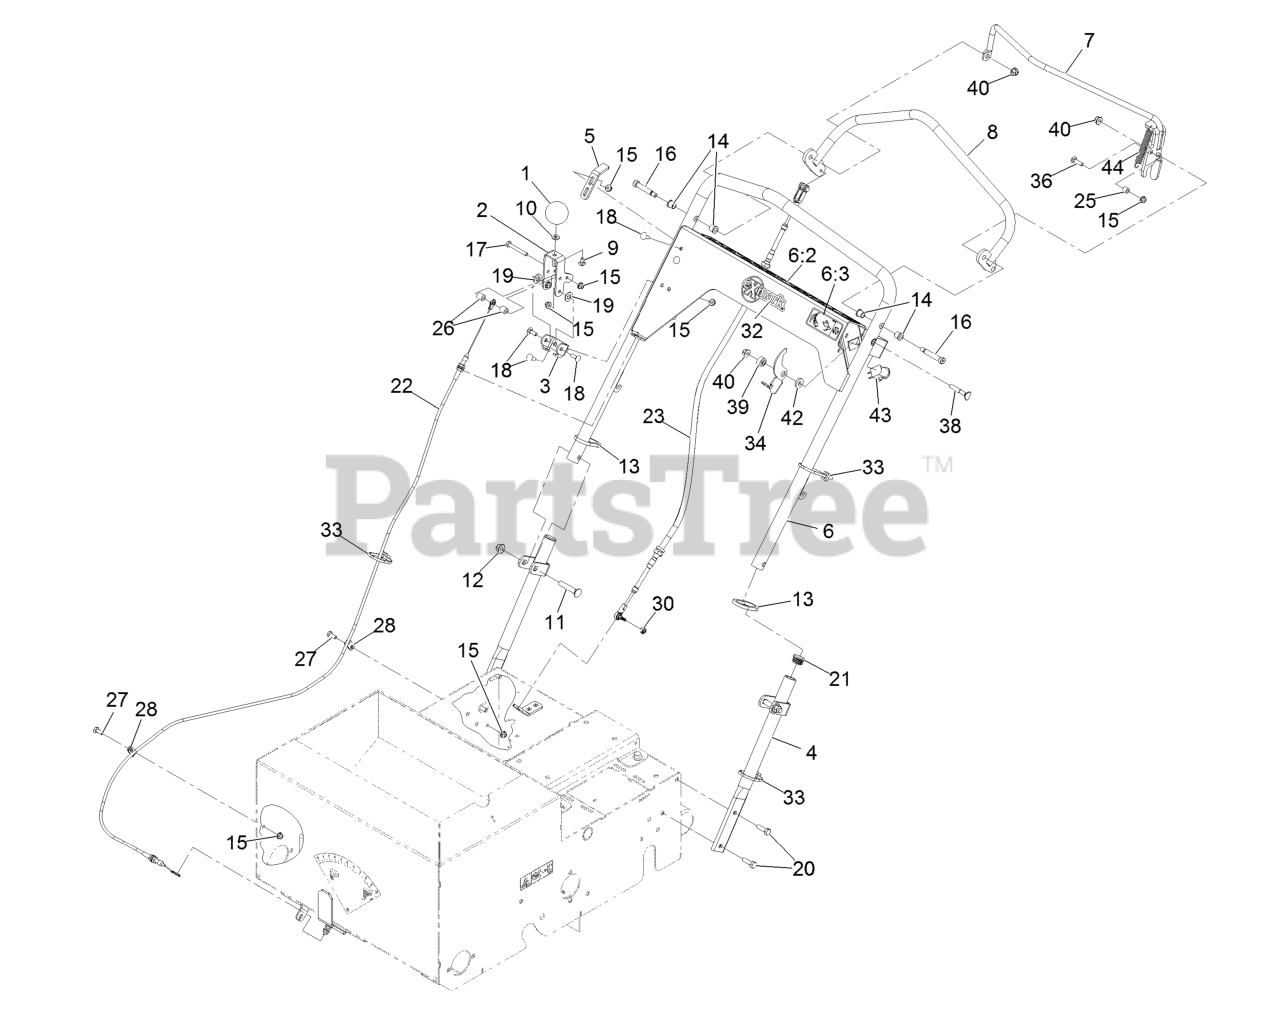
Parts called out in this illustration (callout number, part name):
1	KNOB-RATE, FLOW
2	LEVER-ADJUST, FLOW
3	BRACKET-ADJUST, FLOW
4	HANDLE-LOWER
5	BRACKET-ADJUST, DRIVE
6:2	DECAL-CONTROL PANEL, SEED
6:3	DECAL-SAFETY LATCH
8	HANDLE-DRIVE
9	SCREW-CARR
10	WASHER-FLAT
11	SCREW-HH
12	NUT-HF, NI
13	RING-HANDLE LOCK
14	BEARING
16	SCREW-SHOULDER
17	SCREW-HH
18	BOLT-CARR
19	WASHER-PLAIN
20	SCREW-HH
22	CABLE-FLOW, SEED
23	CABLE-PUSH PULL
27	SCREW-HH
28	CLAMP-R
30	NUT-LOCK
33	TIE-CABLE
34	LATCH-BAIL
36	SCREW-CARR
39	BUSHING-STEPPED
40	NUT-HF, NI
42	WASHER-FLAT
43	SWITCH-BAIL
